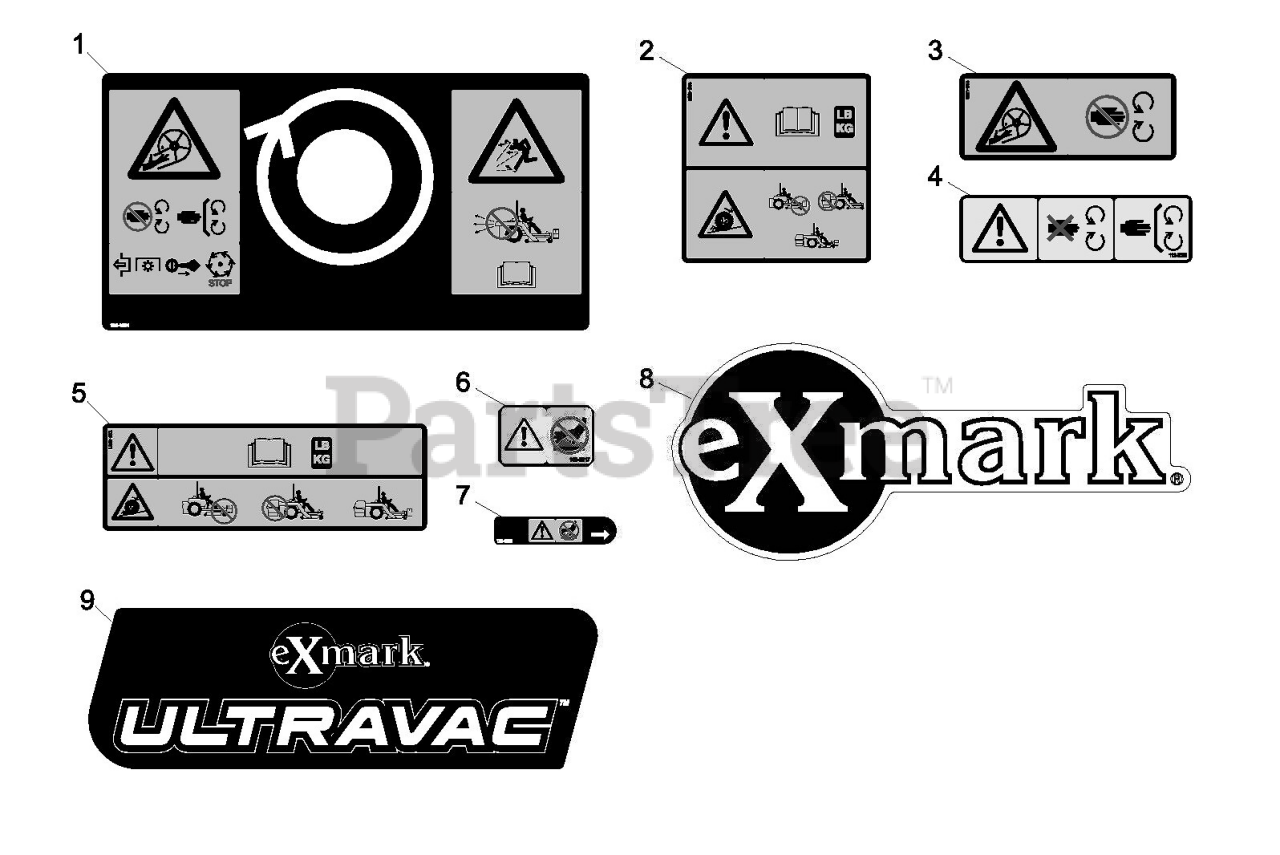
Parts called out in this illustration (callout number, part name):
1	Decal-Warning Blower
2	Decal-Warning Traction
3	Decal-Blower Impeller Hazard
4	Decal-Cover Missing
5	Decal-Warning Weight
6	Decal-Hot Surface
7	Decal-Hot Pulley
8	Decal-Exmark (52)
9	Decal, Ultra Vac
